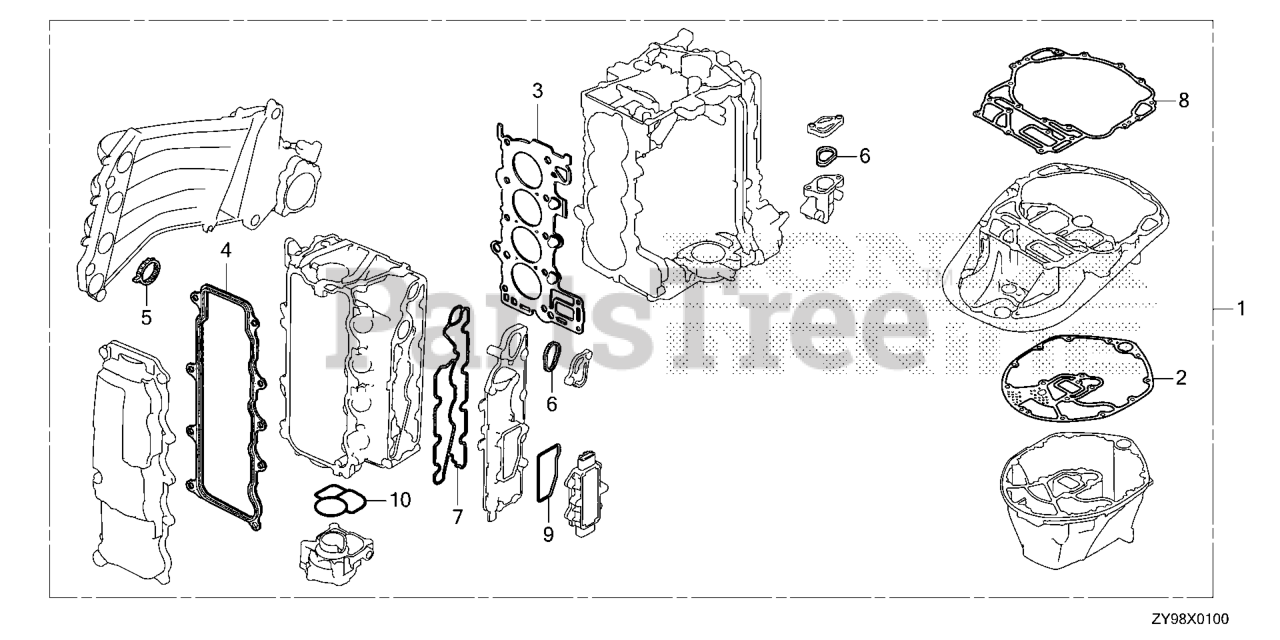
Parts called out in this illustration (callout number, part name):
1	GASKET KIT
2	GASKET, OIL PAN
3	GASKET, CYLINDER HEAD
4	GASKET, HEAD COVER
5	GASKET, IN. MANIFOLD
6	O-RING, THERMOSTAT COVER
7	GASKET, EX. WATER JACKET COVER
8	GASKET, MOUNT CASE
9	GASKET, REGULATOR
10	O-RING, OIL PUMP
